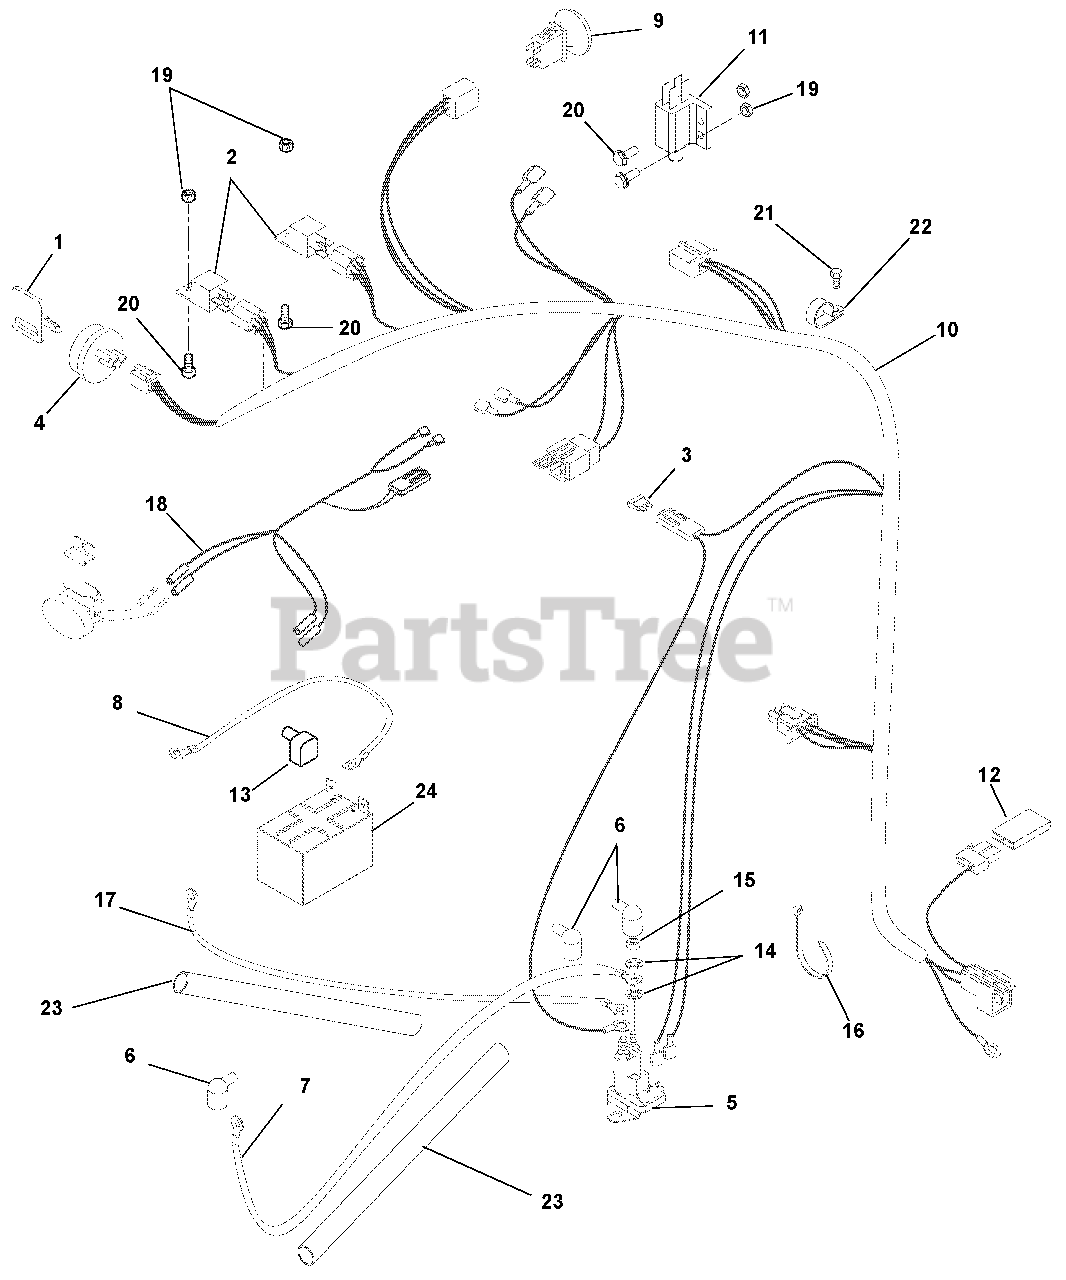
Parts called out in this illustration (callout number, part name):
1	KEY -W/CAP
2	RELAY
3	FUSE-25 AMP ATC TYPE
4	KEY SWITCH
5	SOLENOID, HP RTV
6	BOOT, EYELET TERMINAL
7	STARTER CABLE
8	CABLE-GROUND .25 X 13.00 X .31
9	SWITCH, CLUTCH
10	HARNESS, ZTXL/ZOOMXL
11	SWITCH- DOUBLE POLE N.O./N.O.
12	DIODE, CONNECTOR SHELL
13	INSULATOR
14	WSHR-LOCK INT .31 YWZC
15	NUT-JAM .31-24 YWZC
16	CABLE TIE LG 5-1/2
17	POSITIVE CABLE
18	HARNESS, XL HEADLIGHT
19	@NUT-LK-NYL 10-24 W/INSRT YWZC
20	@SCR-MCH 10-24X.75 HWH YWZC
21	@SCR-TAP .38-16X.50 HWH TR YWZ
22	CLAMP, CUSHIONED STEEL .75
23	SLEEVE, ANTI-ABRASION
24	BATTERY, 12V; 215 CCA GEP
